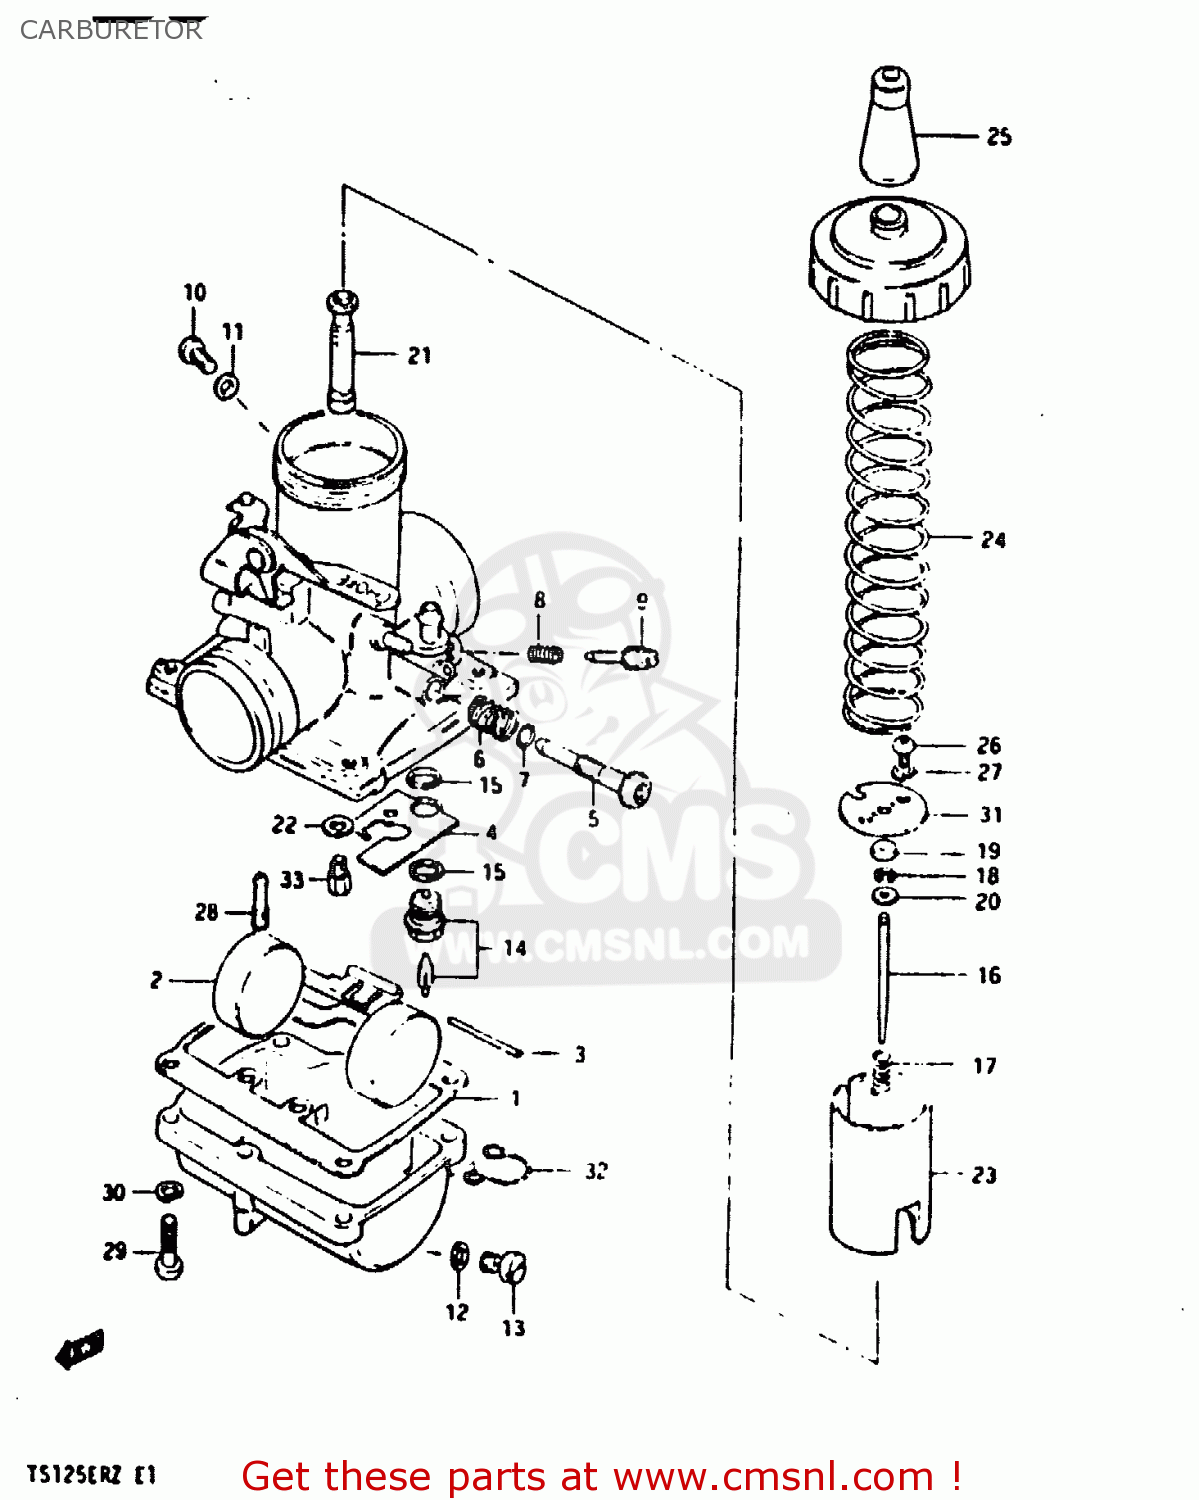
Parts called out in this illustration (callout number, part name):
1	GASKET,FLOAT CHAMBER (NAS)
2	FLOAT
3	PIN,FLOAT
4	PLATE
5	SCREW,THROTTLE STOP
6	SPRING,PILOT
7	O RING
8	SPRING,THROTTLE SCREW
9	SCREW,PILOT AIR
10	SCREW
11	GASKET,DRAIN PLUG (NAS)
12	GASKET,DRAIN,PLUG (NAS)
13	PLUG
14	VALVE ASSY,NEEDLE
15	GASKET,VALVE SEAT (NAS)
16	NEEDLE, JET (5F55-3)
17	SPRING
18	CLIP
19	RING
20	WASHER
21	JET, NEEDLE (0-4)
22	WASHER,JET NEEDLE
23	VALVE,THROTTLE
24	SPRING
25	CAP,RUBBER
26	SCREW
27	LOCK WASHER
28	JET
29	SCREW
30	LOCK WASHER
31	SEAT, THROTTLE VALVE SPRING
32	CLIP
33	JET
